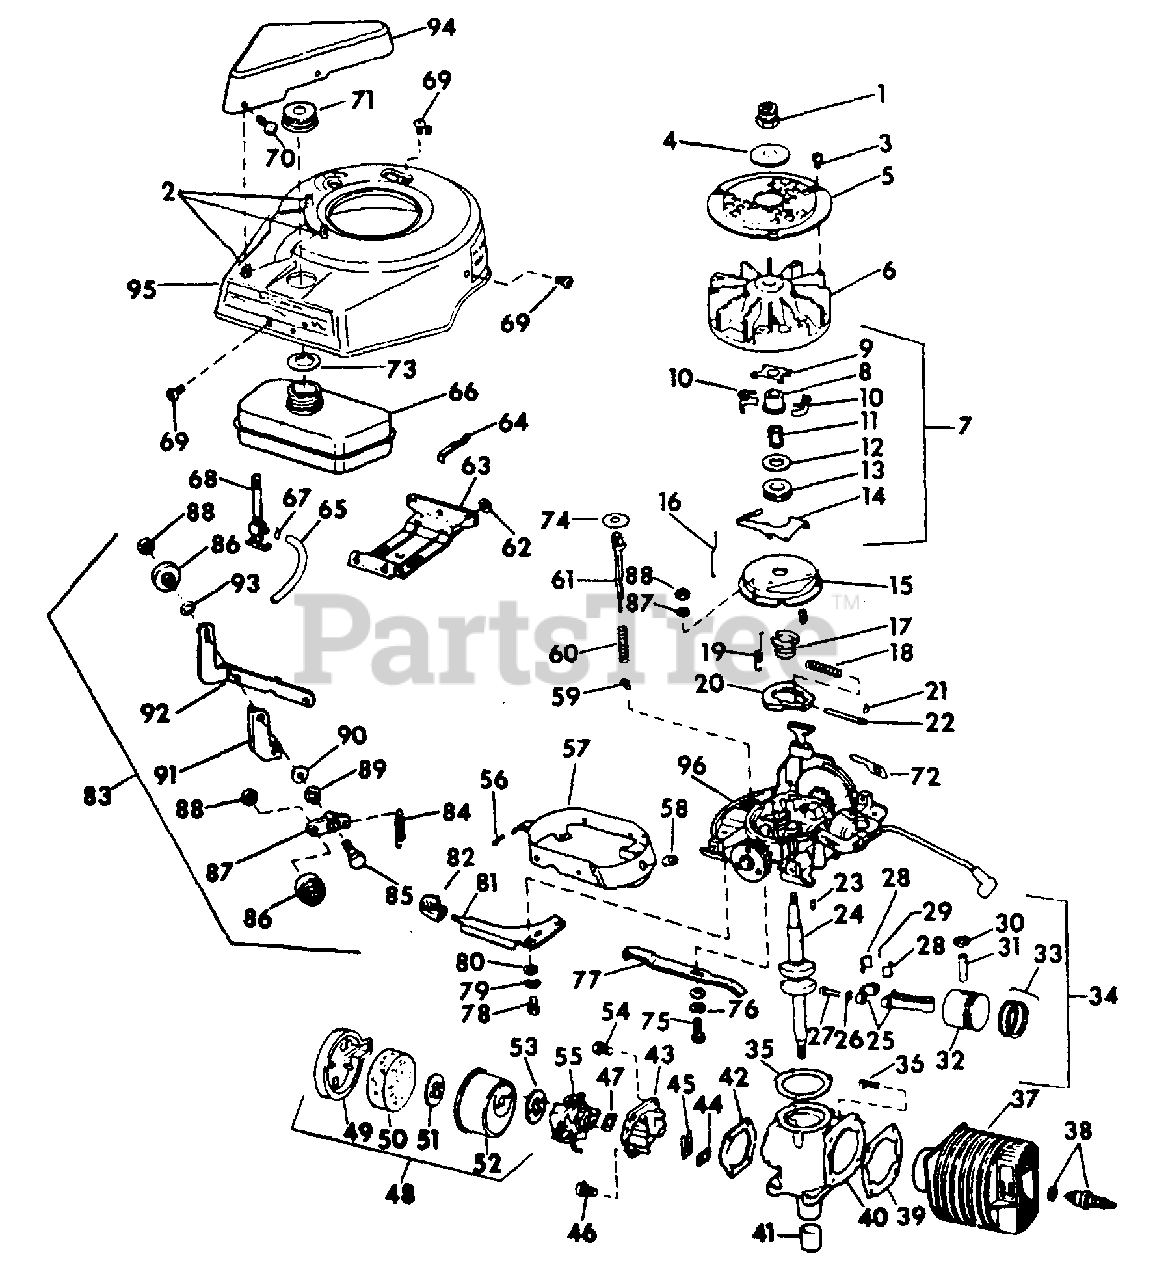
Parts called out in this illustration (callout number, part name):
1	PULLEY, DRIVE
3	SCREW, THD CUTTING
5	SCREEN, FLYWHEEL
7	GOVERNOR ASSY
8	COLLAR, GOVERNOR
9	YOKE, GOVERNOR
10	WEIGHT, GOVERNOR
11	SPRING, GOVERNOR
12	WASHER, THRUST
13	COLLAR, THRUST
14	LEVER, GOVERNOR
16	ROD, GOVERNOR
17	CAM, SPARK ADVANCE
18	SPRING, SPARK ADVANCE
19	SPRING, VARIABLE SPEED
20	FLYWHEEL, SPARK ADVANCE
21	RETAINER, SPRING
22	PIN, SPARK ADVANCE
23	KEY, CRANKSHAFT
25	ROD ASSY, CONNECTING
26	LOCKPLATE, SCREW
27	SCREW, CONNECTING ROD
28	LINER, CONNECTING ROD
29	BEARING SET, NEEDLE - PACKED
30	RING, RETAINING
33	RING SET, PISTON
34	PISTON & CONNECTING ROD ASSY
35	GASKET, CRANKCASE TO ARM PLATE .010
36	SCREW. CYL TO CRANKCASE
37	CYLINDER & SLEEVE
38	SPARK PLUG & GASKET
39	GASKET. CYL TO CRANKCASE
40	CRANKCASE & SEAL ASSY
42	GASKET, REED PLATE
43	REED PLATE ASSY
44	PLATE, BACKUP
46	SCREW, HH REED PLATE TO CRANKCASE
47	GASKET, CARBURETOR
48	FILTER ASSY, AIR
49	CAP - PAINTED WHITE
50	ELEMENT, AIR CHAMBER
52	CHAMBER, AIR - PAINTED WHITE
54	SCREW, HH REED PLATE TO CRANKCASE
55	CARBURETOR ASSY
56	NUT, COVER MTG
58	GROMMET, COVER MTG
59	BLADE, SWITCH
60	SPRING, SHUTOFF SWITCH
61	BAR, SHUT-OFF & PRIMER
63	BRACKET, FUEL TANK
64	SPRING, FUEL TANK
66	FUEL TANK ASSY
67	CLAMP, HOSE
68	VALVE & SCREEN, SHUT-OFF
69	SCREW, COVER MTG
71	CAP, GAS TANK
73	GASKET, TANK TO SHROUD
74	NOT USED ON THIS APPLICATION
75	SCREW, SHOULDER
76	WASHER, SPRING
77	LINK, VARIABLE SPEED CONTROL
78	BOLT, SHOULDER SLOT
80	WASHER, PLAIN
81	LEVER, VARIABLE SPEED
82	KNOB, VARIABLE SPEED LEVER
83	IDLER BRACKET PULLEY ASSY
85	BOLT, SHOULDER
86	PULLEY & BRG
88	NUT, CENTERLOCK
91	BRACKET, SPRING RETINER
92	BRACKET, IDLER
94	COVER, BELT - PAINTED WHITE
95	COVER ASSY, ENGINE
96	MAGNETO ASSY
